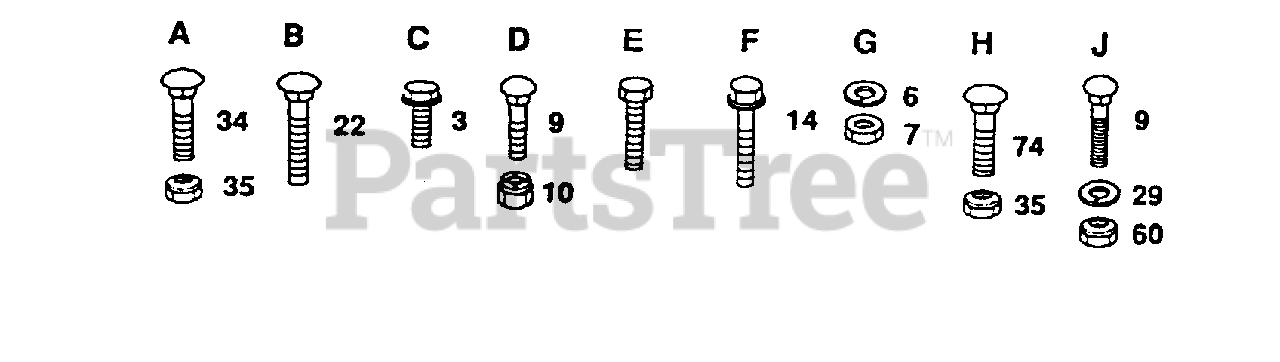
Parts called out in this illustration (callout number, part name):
3	Screw - Hex Washer Thrd. Roll 5/16 18 x 1/2
6	Washer- Lock, 5/16
7	Nut- Hex 5/16- 18
9	Bolt, Carr. 5/16-18 x 3/4
10	Nut, Lock 5/16- 18
14	Screw- Hex Washer Thrd. Roll 3/8 16x3/4
22	Bolt, Carriage 5/16-18 x 2 - 3/4
29	Washer 11/32 x 3/4 x 16 Ga
34	Bolt, Carriage 3/8 - 16 x 3/4
35	Nut, Crownlock 3/80 16
60	Locknut 5/16 -18
74	Bolt, Carriage 3/8 -16 x 1
